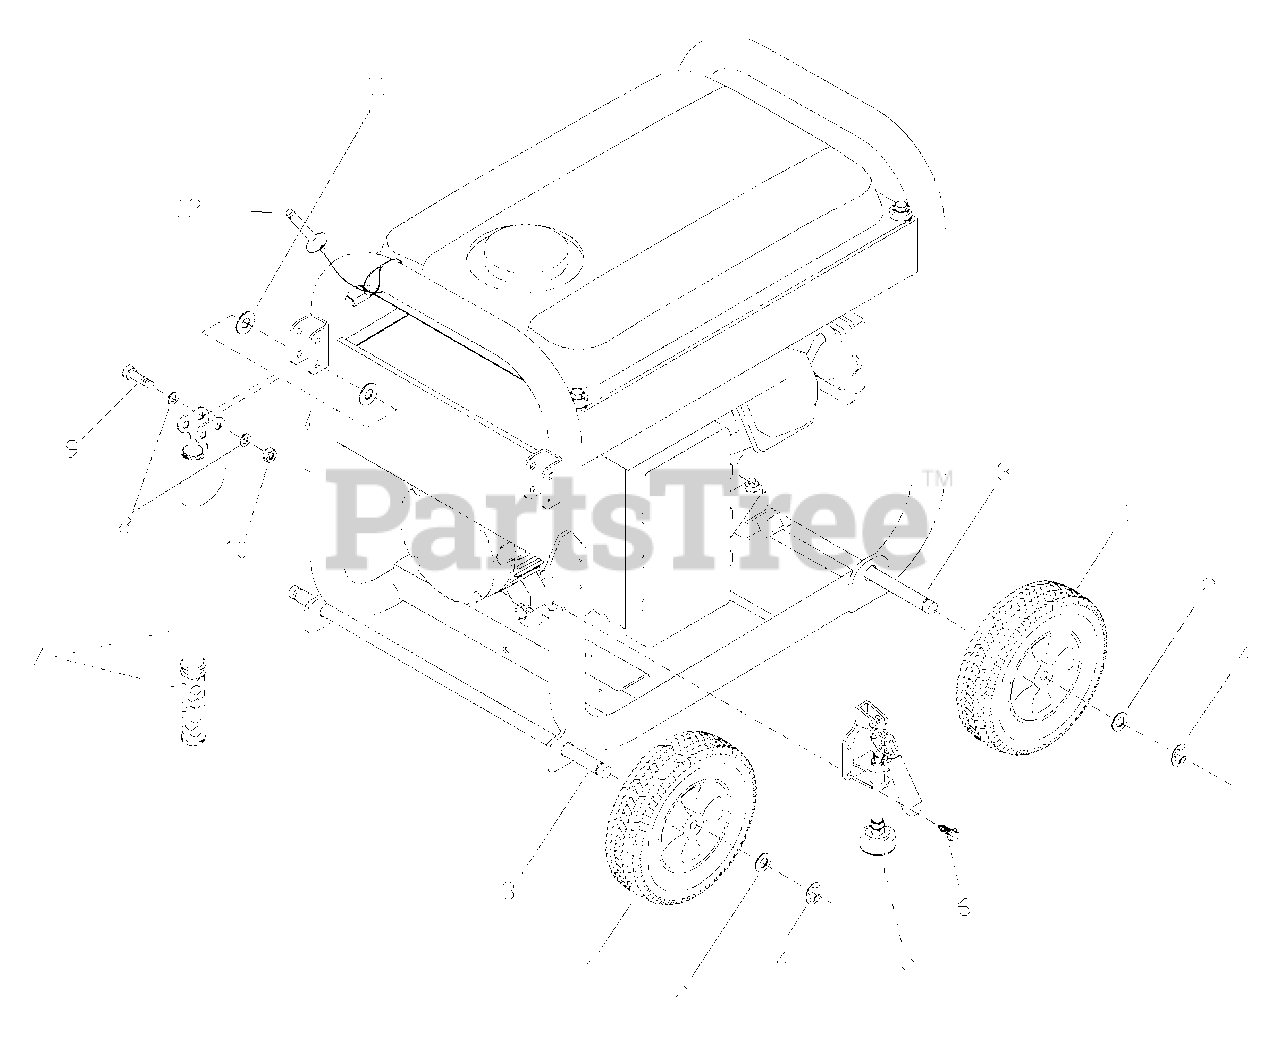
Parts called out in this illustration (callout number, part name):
2	*WASHER, 5/8
4	E-RING
6	*SCREW-1/4-20 x 3/8
8	*WASHER, Flat, 5/16-M8
9	*NUT, Nylock, M8 - 1-1/4
10	*CAPSCREW, Hex Head, M8 - 1-1/4 x 45
11	*WASHER, Nylon, 1.2 x 0.346 x 0.03
